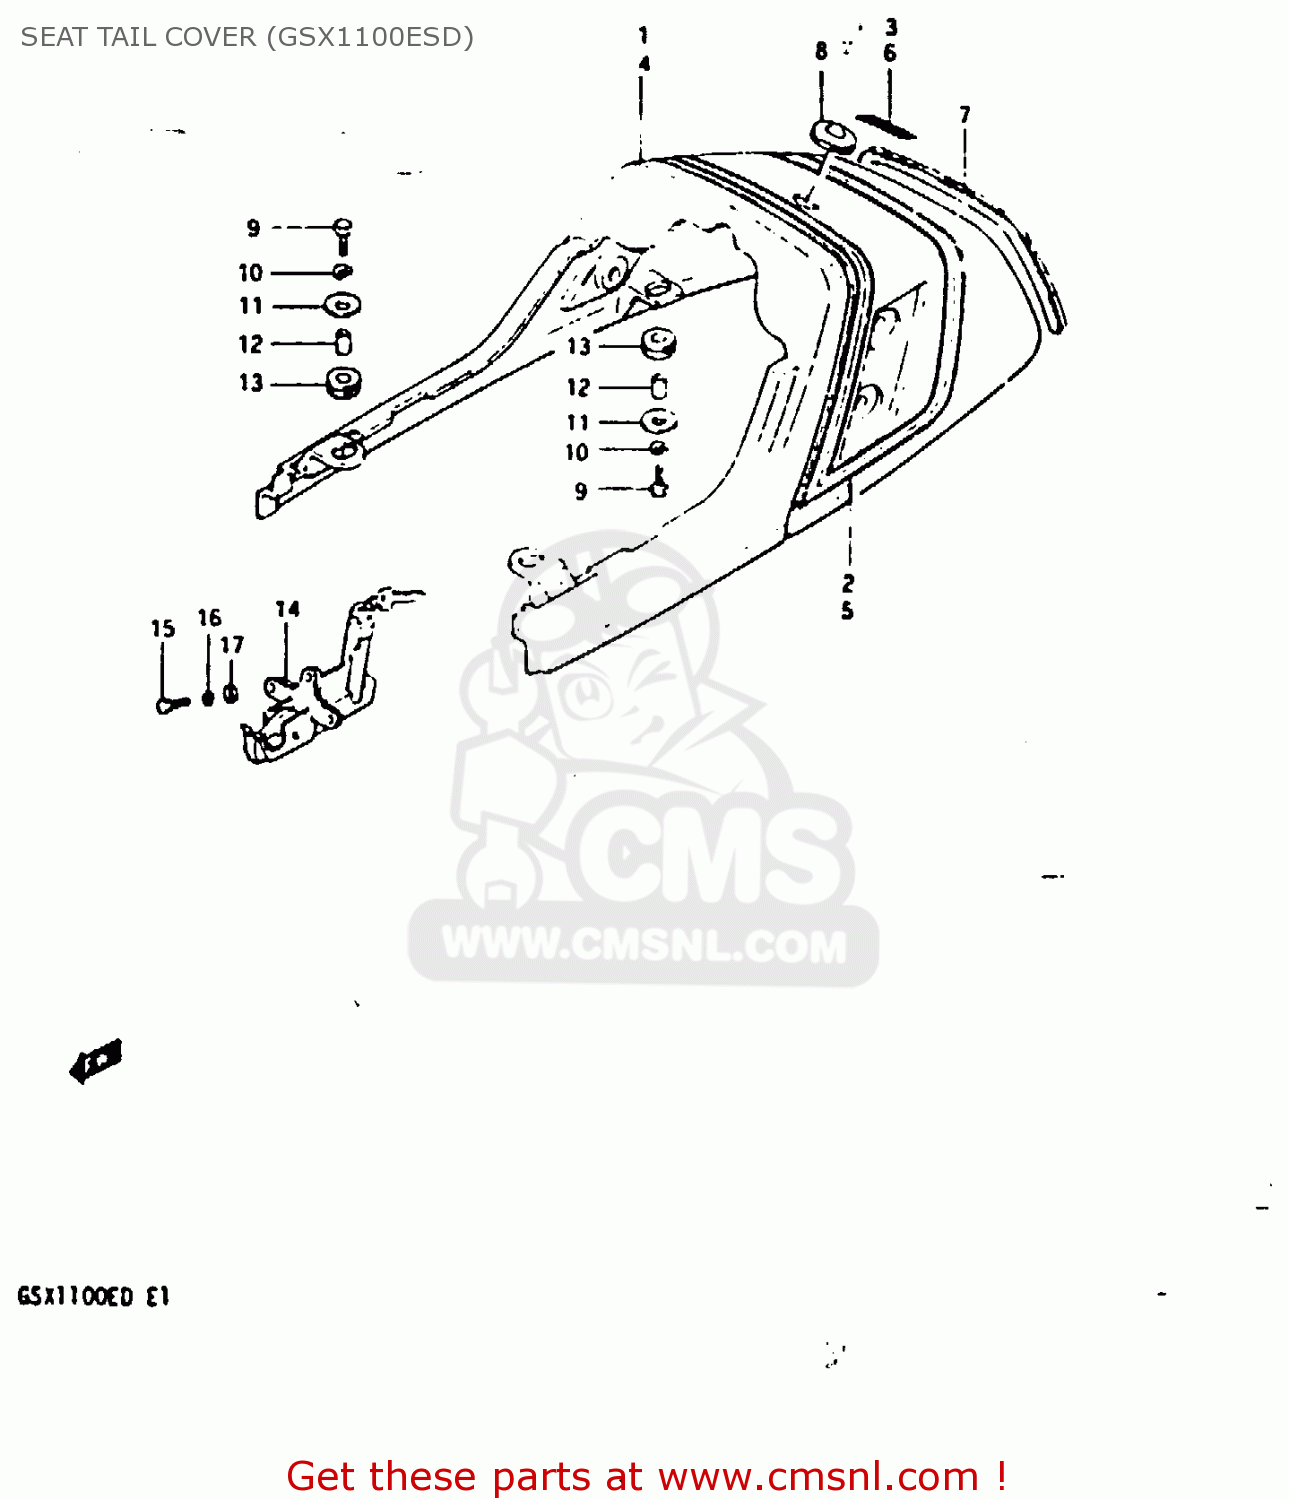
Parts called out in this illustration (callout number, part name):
1	COVER,SEAT TAIL
2	TAPE SET,SEAT TAIL COVER
3	EMBLEM
4	COVER,SEAT TAIL
5	TAPE SET,SEAT TAIL COVER
6	EMBLEM
7	RUBBER,BLIND,SEAT TAIL COVER
8	GROMMET,SEAT LOCK HOLE
9	BOLT
10	LOCK WASHER
11	WASHER(6,5X22X1.6)
12	SPACER(6.5X10.5X12)
13	CUSHION
14	LOCK SET,SEAT
15	BOLT
16	LOCK WASHER
17	WASHER
